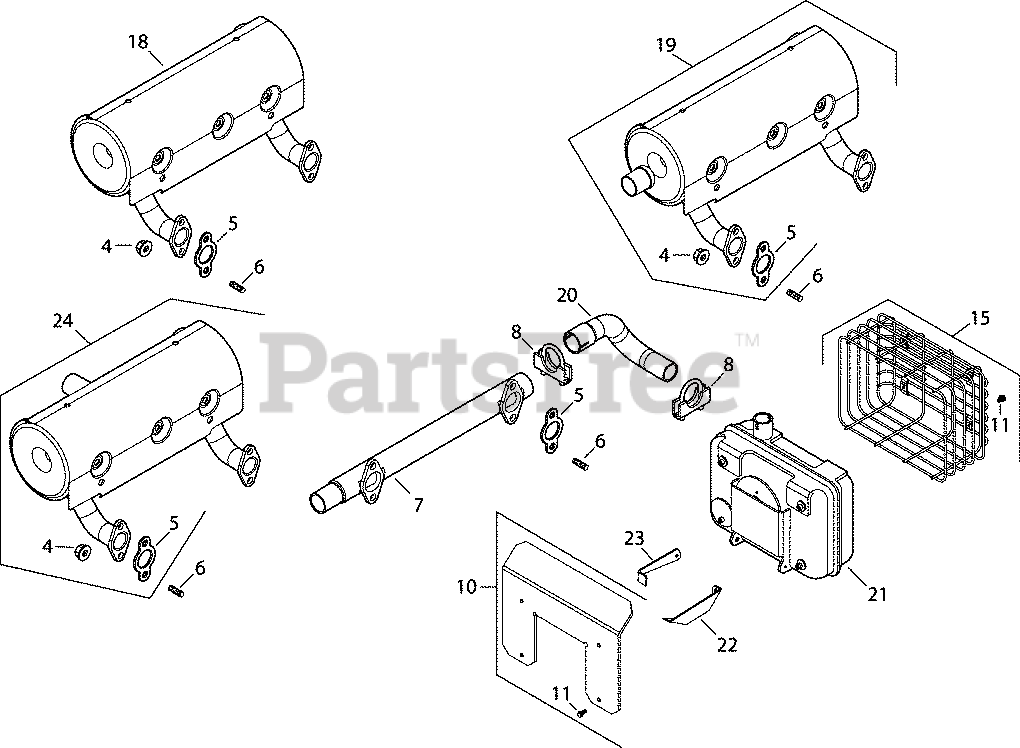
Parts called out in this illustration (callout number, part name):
20	PIPE, EXHAUST NO. 1 - (#DSC)
21	MUFFLER, STARTER SIDE USE 24 068 152-S
22	BRACKET, FRONT MUFFLER
23	BRACKET, REAR MUFFLER
